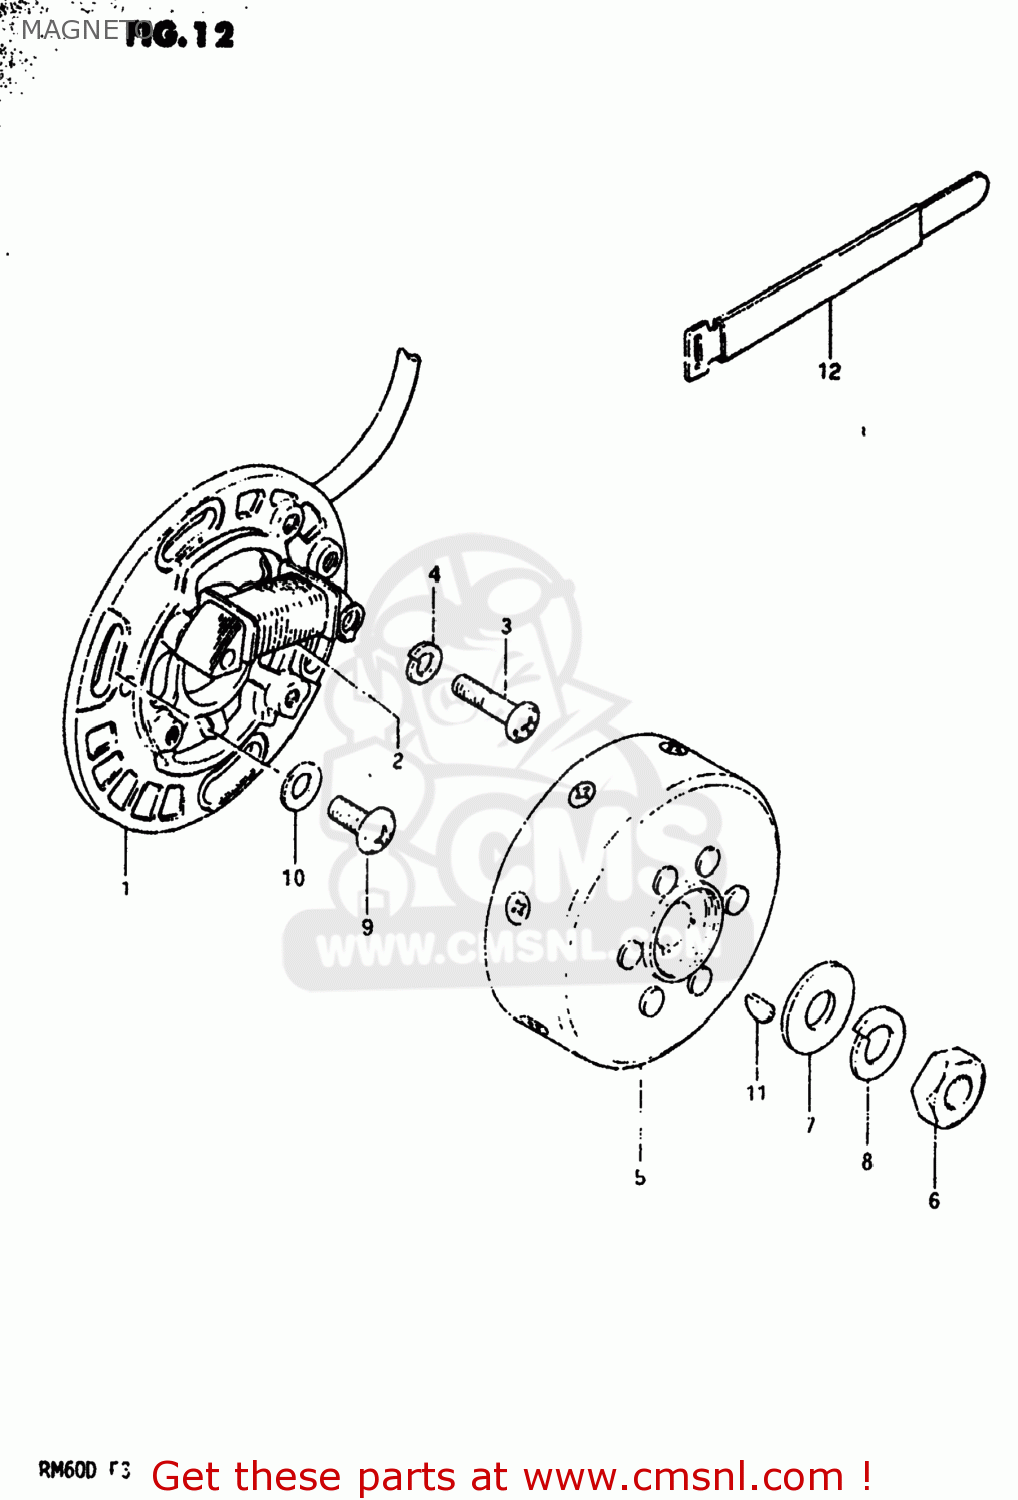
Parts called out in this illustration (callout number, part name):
1	STATOR ASSEMBLY
2	COIL,PRIMARY
3	SCREW 4X25
4	LOCK WASHER
5	ROTOR ASSEMBLY
6	NUT (10MM)
7	WASHER
8	LOCK WASHER
9	SCREW
10	WASHER
11	KEY
12	CLAMP
